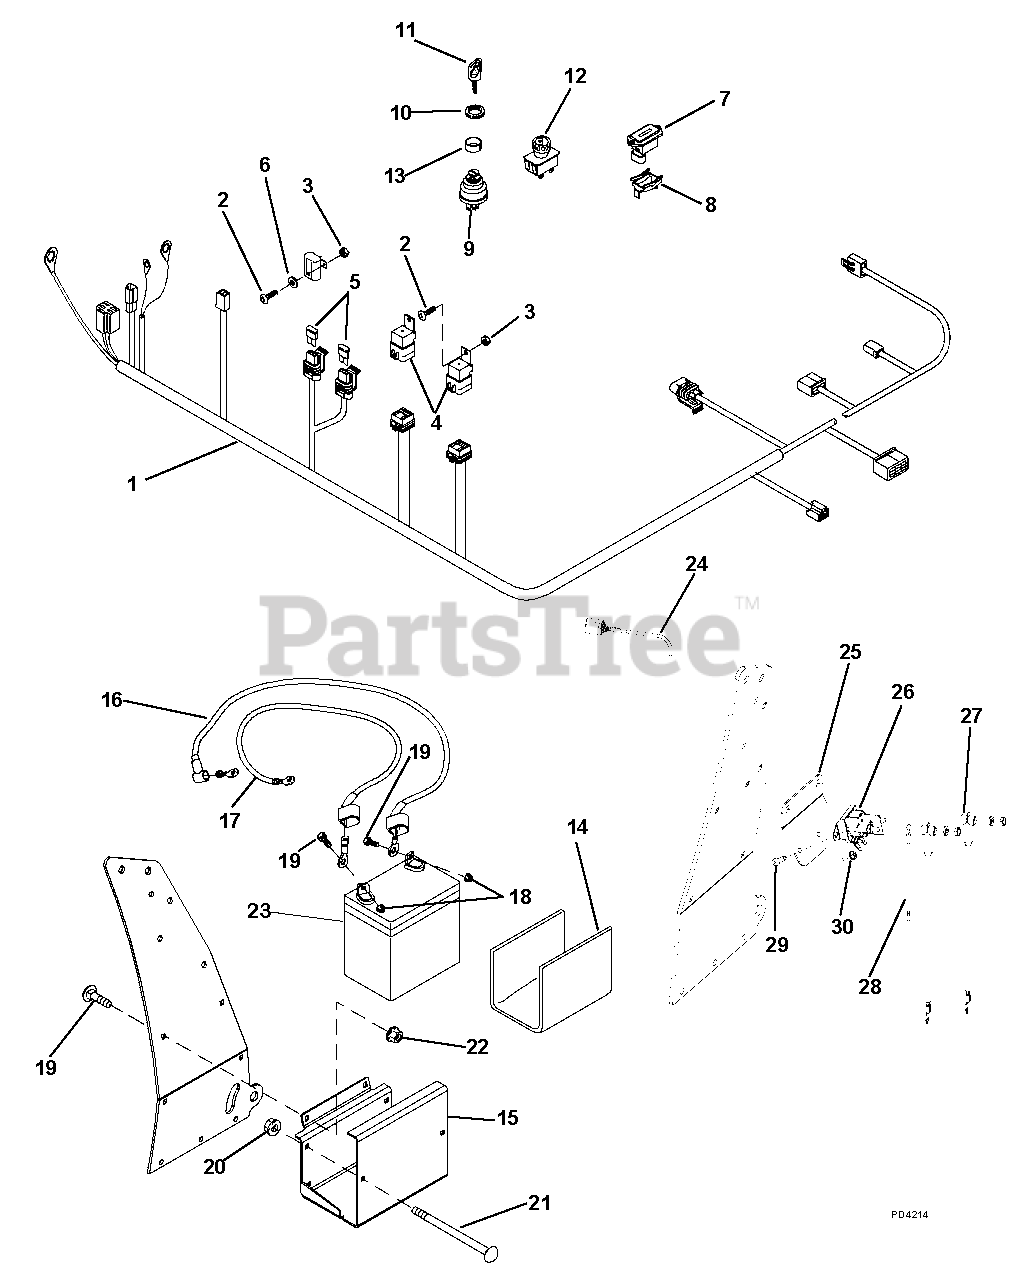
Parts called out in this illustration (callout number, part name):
1	Wiring Harness
2	Bolt, Hex M5-.8 x 16
3	Nut, Hex M5 x .8
4	Relay, Sealed with Bracket
5	Fuse, 20 Amp Blade
6	Washer, Flat Steel .219 x .50 x .049
7	Meter, Hour - LCD
8	Clip, ZTrak Hour Meter
9	Switch, Ignition Key
10	Nut, Knurled
11	Ignition Key
12	Switch, PTO
13	Spacer, 1.00 x .095W x. 392
14	Strip, Rubber
15	Tray, Battery
16	Cable, Battery Starter 48"
17	Cable, Battery 35" Ground
18	Nut, Locking-Flange .25-20
19	Bolt, Hex .25-20 x .75 Grade 5
20	Nut, Locking Nylon M10-1.5
21	Cap Screw 5/16" x 6"
22	Nut, Lock, Nylon M8-1.25
24	Adapter Harness, Kawasaki
25	Solenoid Plate
26	Solenoid
27	Starter Cable, 12"
28	Fusible Link, 10"
29	Bolt, Hex .25-20 x .75
30	Nut, Locking, Flange .250-20
31	Bolt-Round Head Square Neck M8-1.25 x 20
